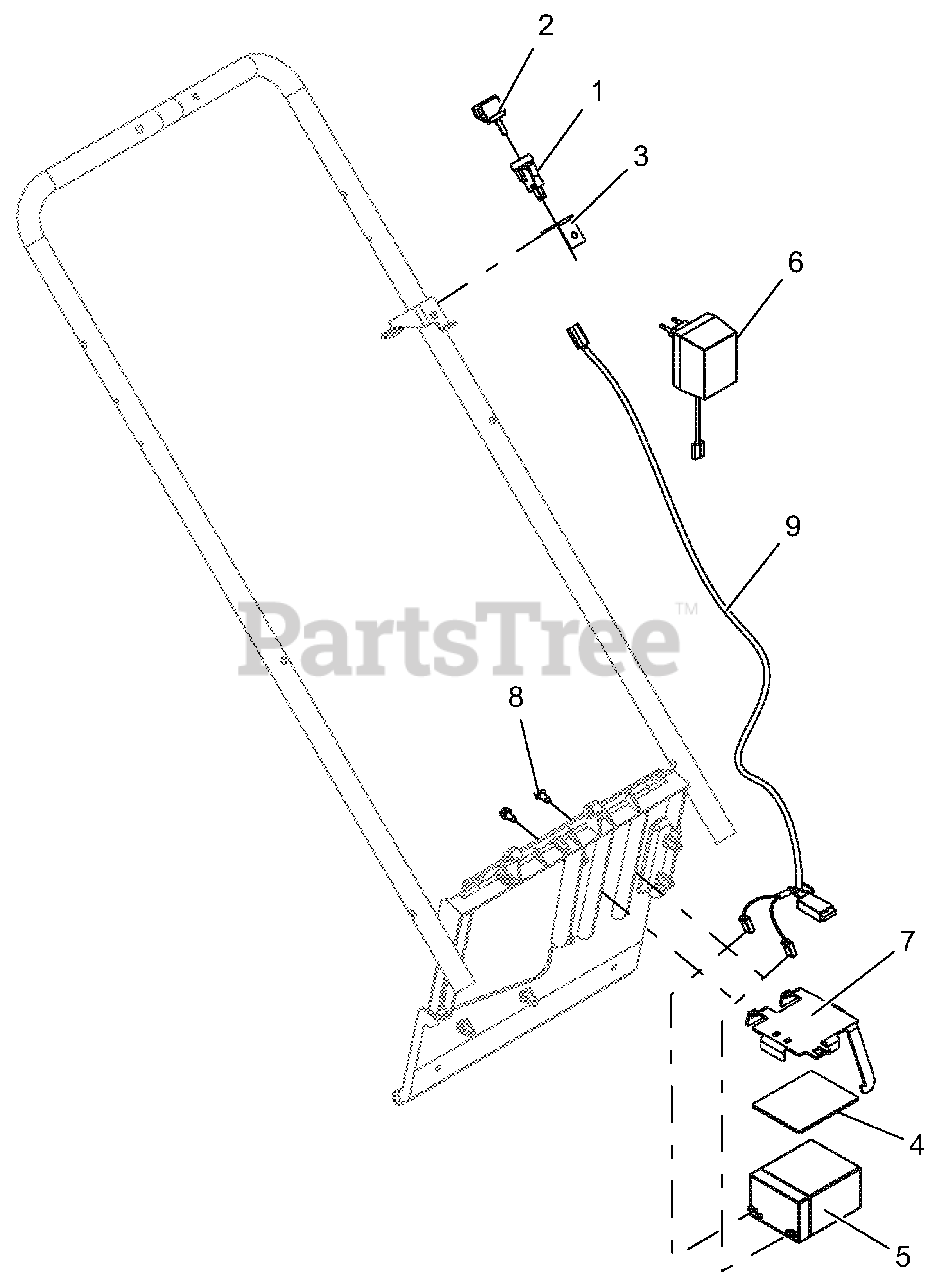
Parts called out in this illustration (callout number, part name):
1	SWITCH, KEY
2	KEYS, IGNITION
3	BRKT, KEY SWITCH
4	PAD, BATTERY, LM
5	BATTERY, AGM, 2.9AH, GNRL PRPS
6	CHARGER, BATTERY - CE
7	BRKT, BATTERY HOLD DOWN
8	SCR-TAP .25-20X.50 HWH TR YWZ
9	HARNESS, ELEC START
